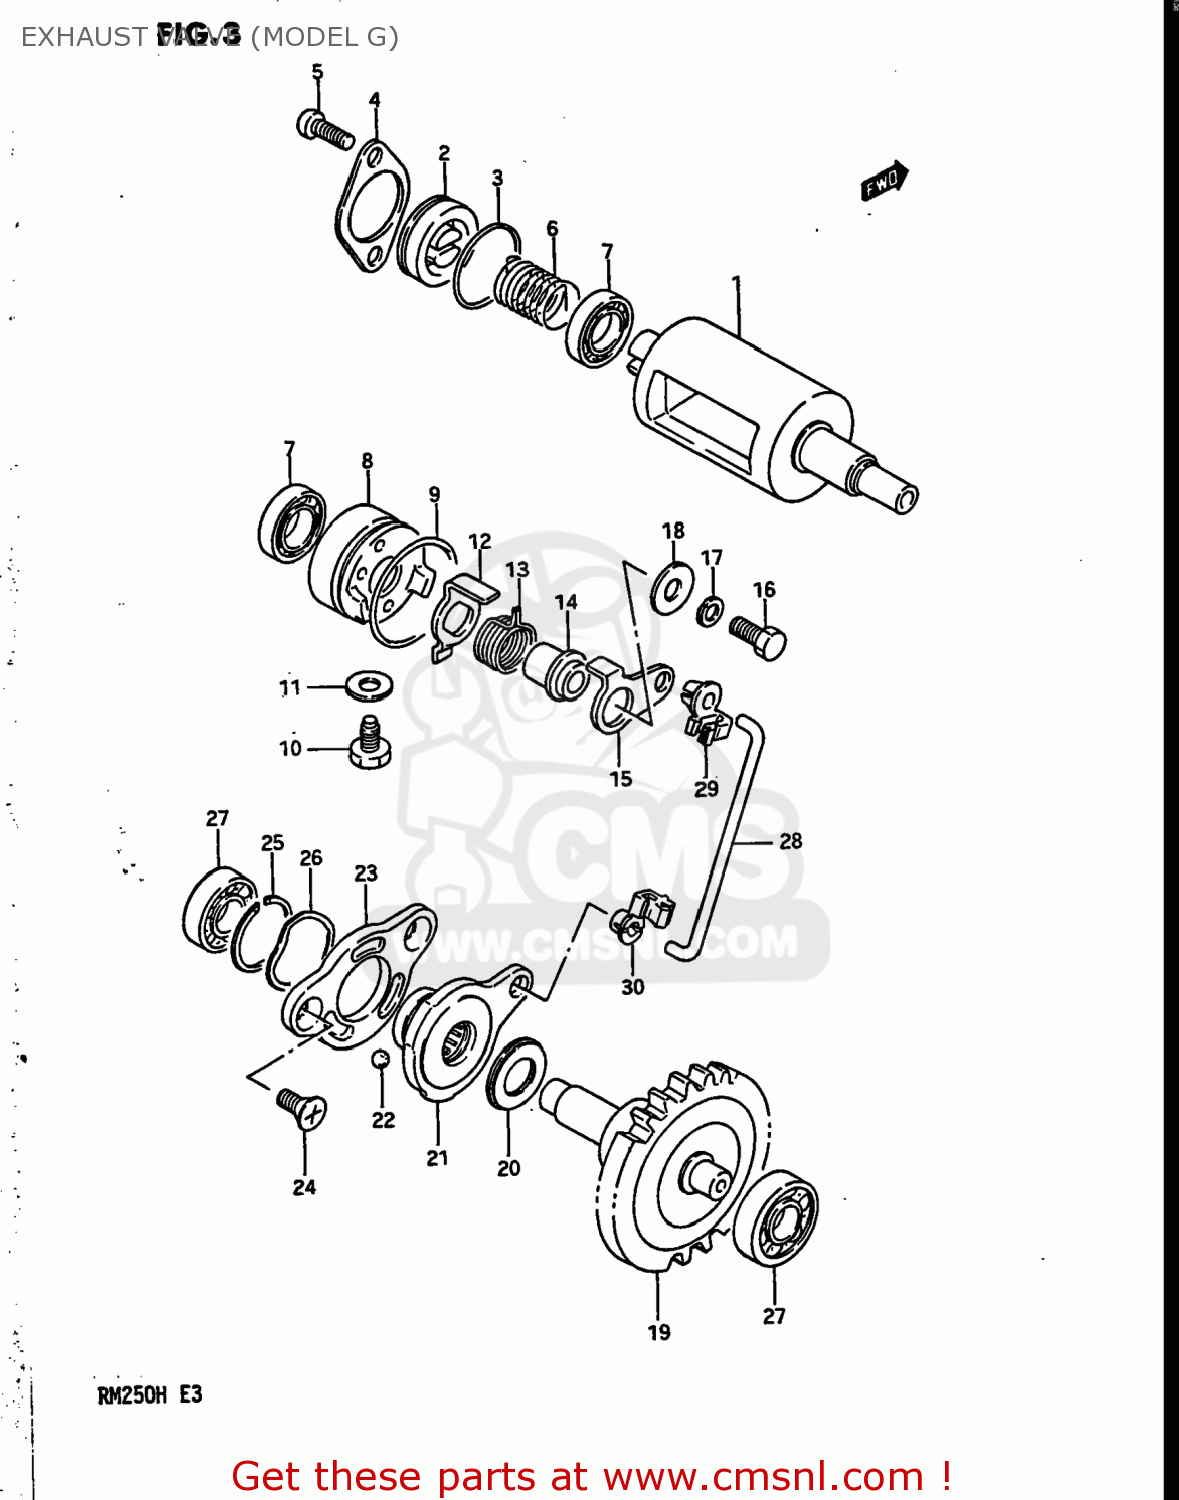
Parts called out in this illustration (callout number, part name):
1	VALVE,EXHAUST
2	CAP,EXHAUST VALVE
3	O RING(D:1.9,ID:22.6)
4	RETAINER,EXHAUST VALVE
5	SCREW
6	SPRING
7	BEARING
8	HOLDER,EXHAUST VALVE
9	O RING(D:2.4,ID:27.7)
10	BOLT
11	GASKET(6.2X11X1).2 (NAS)
12	LEVER,EXHAUST VALVE NO.2
13	SPRING
14	SPACER,EXHAUST VALVE
15	LEVER,EXHAUST VALVE NO.1
16	BOLT
17	LOCK WASHER
18	WASHER (5.5X16X1.2)
19	GOVERNOR ASSEMBLY,EXHAUST
20	BEARING(10X22X2.8)
21	ACTUATOR,EXHAUST VALVE
22	BALL
23	STATOR,EXHAUST VALVE ACTUATOR
24	SCREW(5X10)
25	CIRCLIP
26	WASHER
27	BEARING(8X22X7)
28	ROD,EXHAUST VALVE
29	BUSH,EXHAUST VALVE ROD NO.1
30	BUSH,EXHAUST VALVE ROD NO.2
